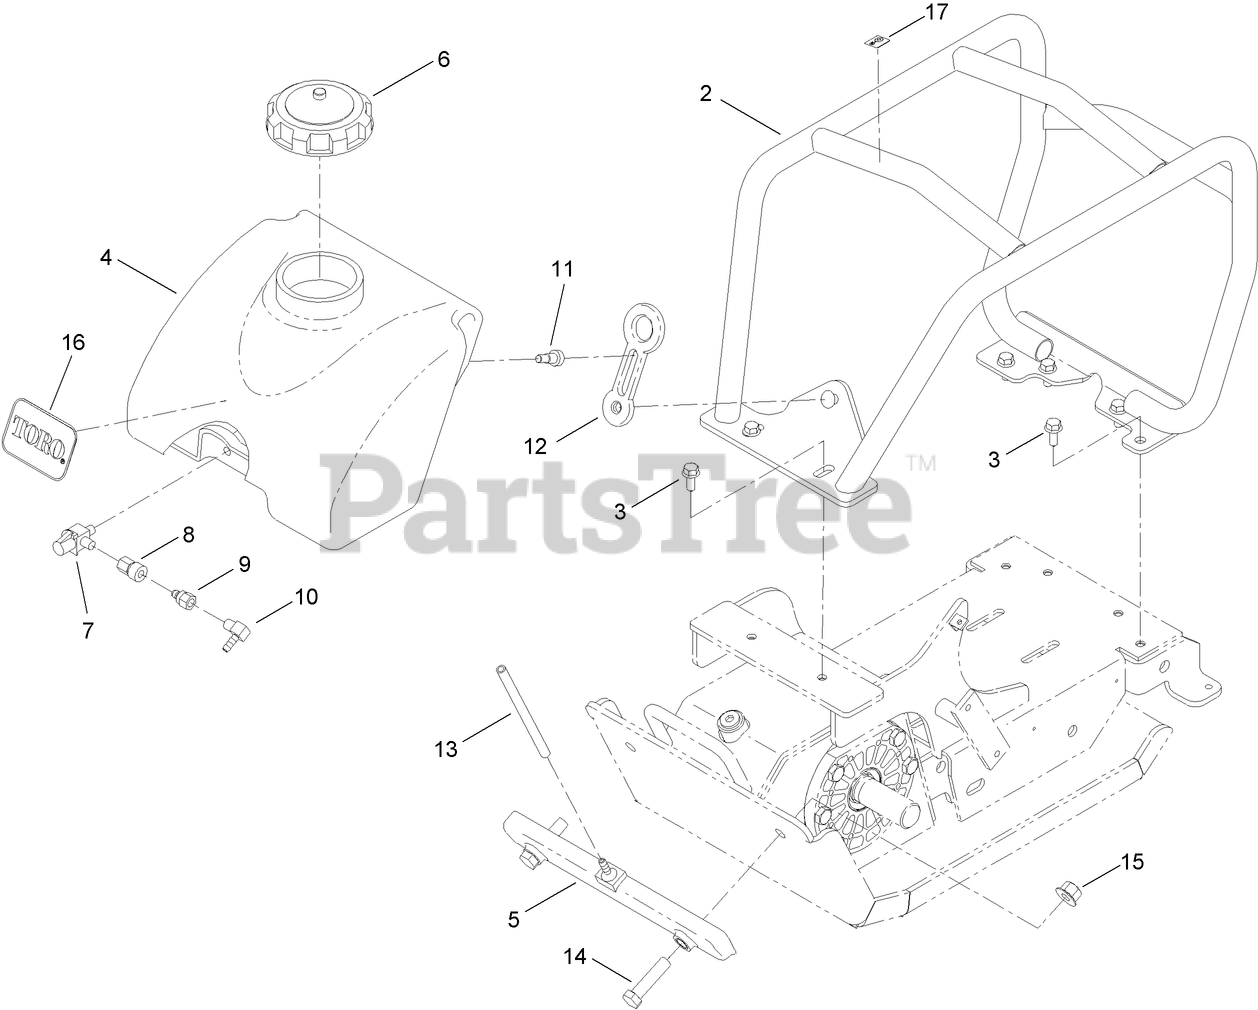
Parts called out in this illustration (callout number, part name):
2	CAGE-ROLL
3	SCREW-HHF
4	TANK-WATER
5	SPRINKLER
6	CAP-PLASTIC
7	VALVE-BALL
8	FITTING-QUICK, FEMALE
9	FITTING-QUICK, FEMALE, NIPPLE
10	FITTING-HYD, 90 DEG
11	SCREW-HSBH
12	LATCH-RUBBER
13	HOSE-WATER
14	SCREW-HH
15	NUT-LOCK, HHF
16	DECAL
17	DECAL-POINT, LIFT
